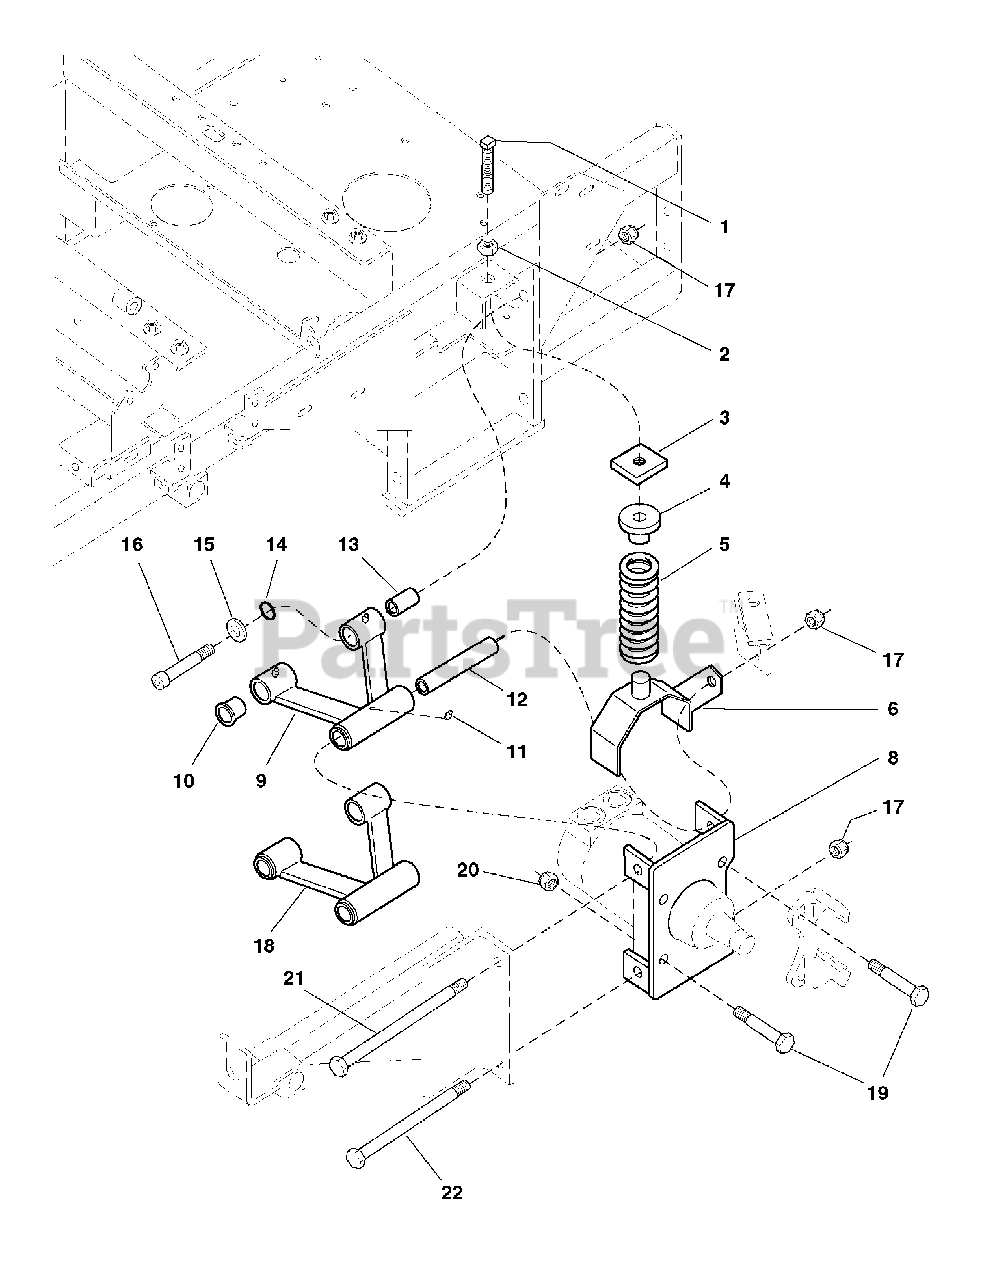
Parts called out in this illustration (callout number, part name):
1	SET SCREW, Square Hd, 1/2-13 x 3
2	NUT, Hex, Jam, 1/2-13
3	SPRING COMPRESSION PLATE
4	SPRING RETAINER
5	SPRING, Suspension
6	SPRING SADDLE-LH
8	WHEEL MOTOR MOUNT
9	SUSPENSION A-ARM, Upper
10	BUSHING, Flange
11	GREASE FITTING
12	PIVOT SLEEVE, Long
13	PIVOT SLEEVE, Short
15	WASHER, A-Arm
16	CAPSCREW, Allen Head, 1/2-13 x 3
17	NUT, Hex, Nylon Lock, 1/2-13
18	SUSPENSION A-ARM, Lower
19	CAPSCREW, Hex Hd, 1/2-20 x 3
20	NUT, Hex, Nylon Lock, 1/2-20
21	CAPSCREW, Hex Hd, 1/2-13 x 7-1/2
22	CAPSCREW, Hex Hd, 1/2-13 x 6-1/2
